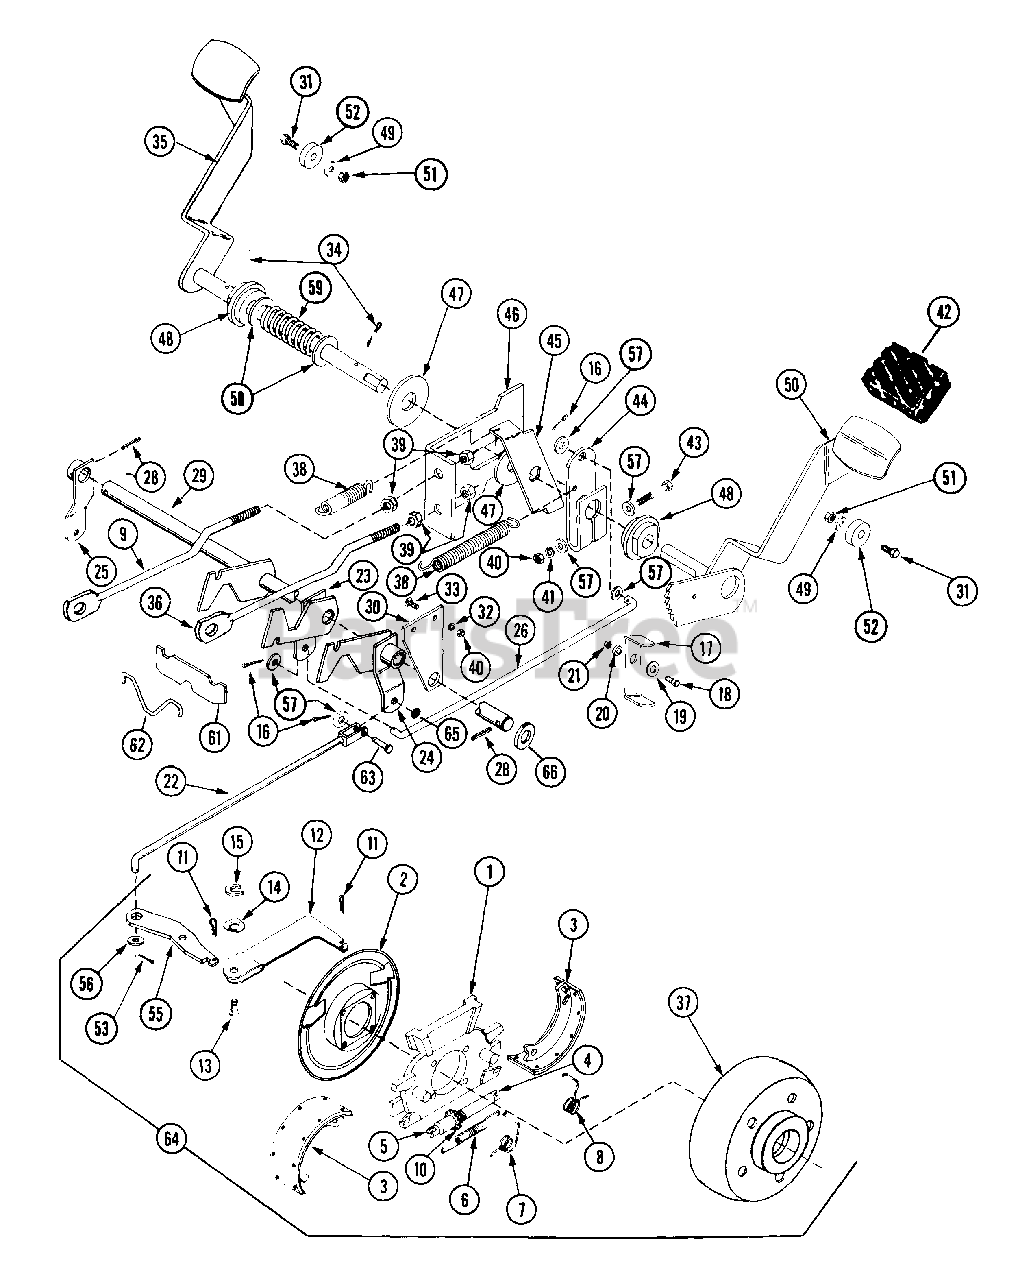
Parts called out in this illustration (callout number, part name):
1	TORQUE SPIDER
2	DUST SHIELD
3	PACKAGE - LINED SHOES
4	PIVOT NUT
5	SOCKET - ADJUSTING SCREW
6	SG-TENS ??X??X?? BENDIX
7	SG-TORS ??X??X?? BENDIX
8	SG-TORS BENDIX 3202132
9	SHIFT ROD
10	ADJUSTING SCREW
11	PIN-HAIR EXT .12X.75
12	STRUT ASSEMBLY
13	CLEVIS PIN
14	WSHR-FL-STL .380X.781X.013 PL
15	RETAINER
16	PIN-COTR .09X.75 PL
17	BRAKE LATCH
18	BLT-HEX .25-20X.75 PL GR2
19	WSHR-FL-STL.281X.62X.065 PL
20	SPACER BUSHING .37 X .26 X .14
21	NUT-LK-CTR .250-20 PL
22	BRAKE ROD
23	BRAKE ARM
25	BRAKE ARM
26	BRAKE ROD
27	PIN-COTR .12X1.0 PL
28	PIN-GRV .250X1.25 TP A
29	BRAKE SHAFT
31	BLT-HEX .31-18X1.00 PL GR 2
32	WSHR-LK .375X.115 HVY PL
33	BLT-RDHDSQSHNK .38-16X1.00 PL
34	PIN-COTR .18X1.25 PL
35	L.H. LEVER
36	NEUTRALIZER ROD
37	BRAKE DRUM
38	SG-TENS .090X.75X3.50 WLD 34
39	NUT-LK-CTR .50-13
40	NUT-HEX .375-16
41	WSHR-LK .375X.094 MED PL
42	PEDAL PAD
43	BLT-HEX .38-16X2.25 GR2
44	ARM-BRAKE
45	NEUTRALIZER ARM
46	NEUTRALIZER PLATE
47	WSHR-FL-STL .755X2.000X.125
48	BSHG-FLG .750X1.750X.875X2.125
49	WSHR-FL-STL .38X.875X.083 PL
50	R.H. LEVER
51	NUT-LK .312-18 GR A PL
52	SPACER .344X1.000X.375
53	PIN-COTR .09X.75 PL
54	WSHR-FL-STL .505X1.000X.062
55	PARKING BRAKE LEVER
56	WSHR-FL-STL .323X.625X.062 PL
57	WSHR-FL-STL.406X.812X.065PL
58	WSHR-FL-STL .755X1.375X.062 PL
59	SG-COMP .148X1.23X2.53 WLD87
60	PIN-HAIR INT .09X.188 PL
61	BALANCE LINK
63	PIN-CLEV .373X1.12 YWZC
64	RH BRAKE ASSEMBLY
64	LH BRAKE ASSEMBLY
65	GROMMET
66	WSHR-FL-STL .754X1.125X.062 PL
